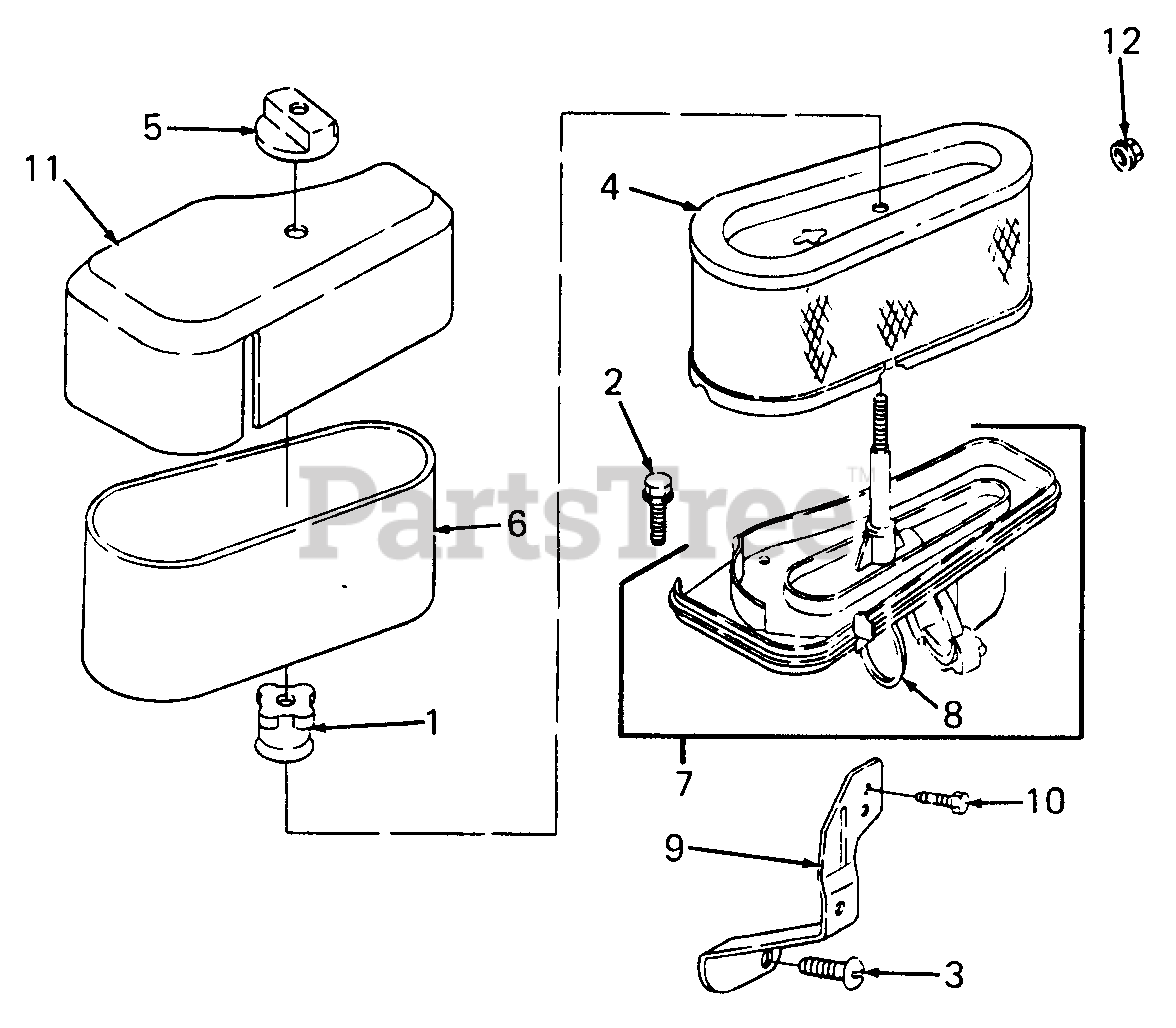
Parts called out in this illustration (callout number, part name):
1	Nut, Air Cleaner Mounting
2	Screw, Air Cleaner Sem
3	Screw, Air Cleaner
4	Cartridge, Air Cleaner
5	Knob, Air Cleaner
6	Element, Air Cleaner
7	Body, Air Cleaner
8	O-Ring, Air Cleaner
9	Brace, Air Cleaner
10	Screw, Hex Hd
11	Cover, Air Cleaner
12	Locknut, Air Cleaner Mounting
